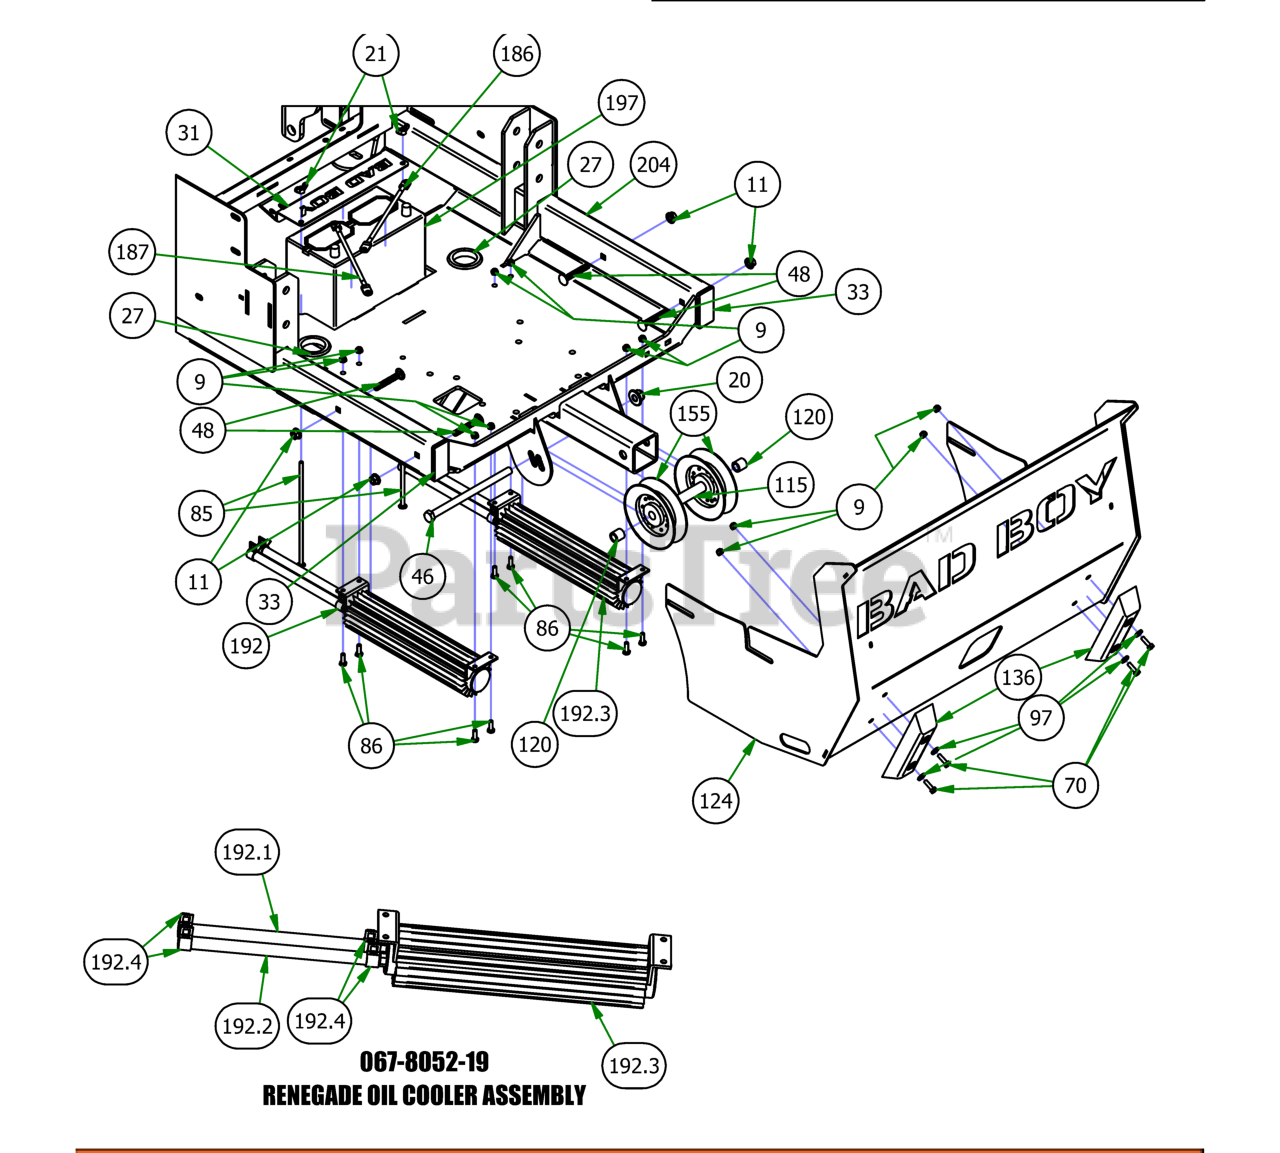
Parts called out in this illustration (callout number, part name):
9	1/4-20 Hex flang lock nut
11	3/8-16 NYLON INSERT FLANGE LOCKNUT (GR.F) ZINC
20	1/2-13 NYLON INSERT FLANGE LOCKNUT ZINC
21	1/4" Wing Nut
27	2019 2" x .25 Rubber Grommet
31	2019 Horizontal Battery Hold Down Cover
33	1 1/2 x 3 Frame Plug
46	1/2" x 8 1/2 GR 5 Hex Bolt
48	3/8" x 2 1/2" Carriage Bolt
70	1/4-20 x 1-1/4 GR 5 Hex Bolt
85	1/4" x 1" Carriage Bolt
86	1/4" x 3/4" Hex Bolt
97	1/4" Flat Washer
115	2019 Pulley Spacer .75 x .5 x 4.375
120	Spacer 3/4 OD x 1/2 ID x 3\4 Length
124	2019 Horizontal Suspension Rear Cover
136	8" Rubber Bumper
155	2019 Outlaw Horizontal Rear V Pulley
186	Red Battery Cable - Diesel
187	Black Battery Cable - Diesel
192	Renegade Oil Cooler Assembly
192.1	3/8" Clear Hose
192.2	3/8" Clear Hose
192.3	2019 12" Oil Cooler With Fittings
192.4	3/8" Hose Clamp
197	Battery - Diesel/Renegade Models PF-516
204	2019 Renegade Gas Frame - Powdercoated
